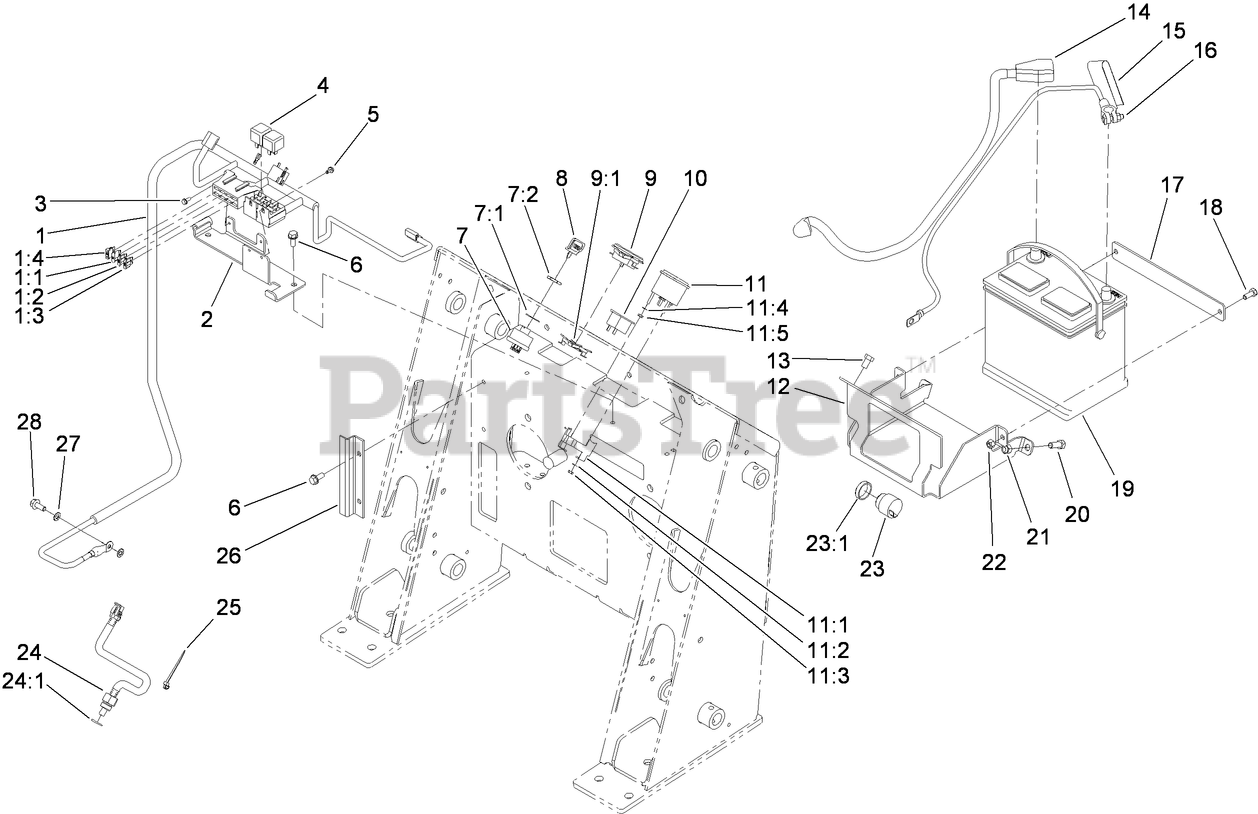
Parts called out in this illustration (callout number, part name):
1	HARNESS-WIRE
1:1	FUSE-BLADE, 10 AMP
1:2	FUSE-BLADE, 25 AMP
1:3	FUSE-BLADE, 30 AMP
1:4	FUSE-BLADE, 15 AMP
2	Fuse/Relay Bracket ASM
3	SCREW-HWH
4	RELAY
5	SCREW-HWH
6	SCREW-HWHTF
7	Key Switch ASM
7:1	WASHER-TOOTH, INTERNAL
7:2	NUT-HH
8	KEY-IGNITION
9	INDUCTIVE HOURMETER ASM
9:1	CLIP-MOUNTING
10	LIGHT-TEMP, OIL
11	GAUGE-FUEL
11:1	BRACKET-MOUNTING, GAUGE
11:2	WASHER-LOCK, INT
11:3	NUT-HEX
11:4	WASHER-LOCK / EXT
11:5	NUT-HEX
12	TRAY-MOUNTING, BATTERY
13	SCREW-HWHTF
14	CABLE-BATTERY, POSITIVE
15	DECAL-INSTRUCTIONS, CHARGING
16	CABLE-BATTERY, NEGATIVE
17	CLAMP-BATTERY
18	SCREW-HH
19	BATTERY
20	SCREW-HH
21	NUT-LOCK, NI
22	NUT-LOCK, NI
23	AUDIO ALARM ASM
23:1	NUT-PLASTIC, KNURLED
24	SENSOR-TEMPERATURE
24:1	O-RING
25	TIE-CABLE
26	SHIELD-WIRING
27	WASHER-LOCK
28	SCREW-HHF
